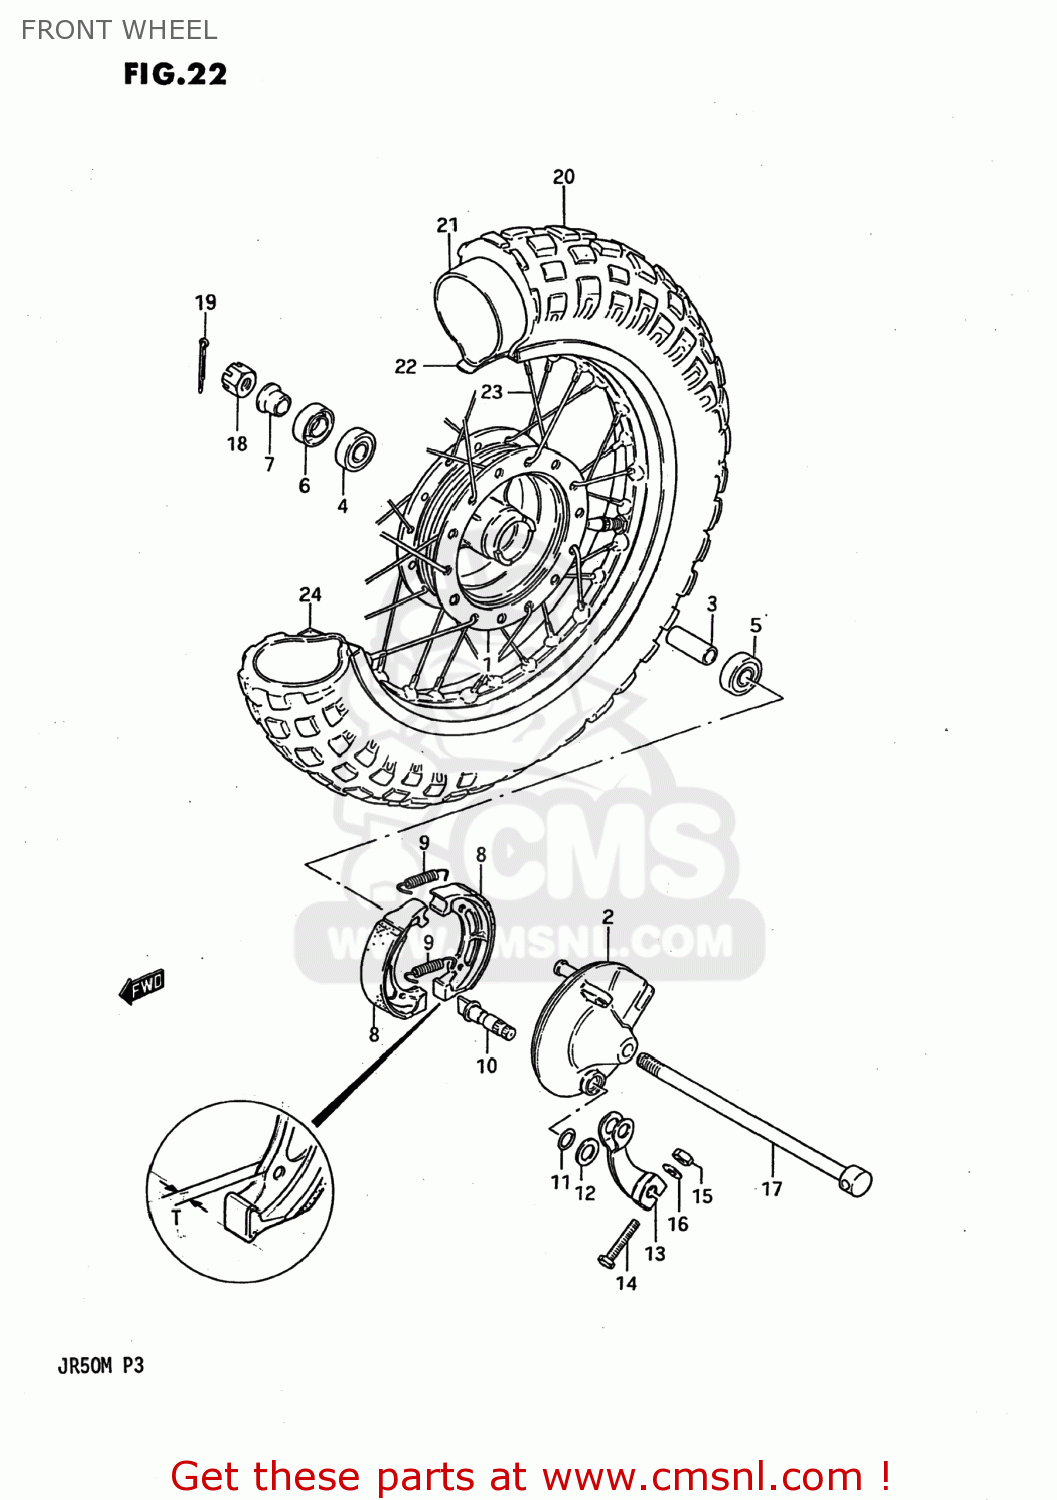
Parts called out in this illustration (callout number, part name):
1	HUB,FR WHEEL
2	PANEL,FR BRAKE ANCHOR
3	SPACER(10.2X16X47)
4	BALL BEARING K
5	BEARING
6	SEAL,OIL(15X27X6)
7	SPACER,AXLE
8	SHOE,BRAKE
9	SPRING(L:34)
10	CAM,FRONT BRAKE
11	O RING(D:2.4,ID:9.8)
12	WASHER (10.5X18X1)
13	LEVER,FR BRAKE CAM
14	BOLT
15	NUT
16	WASHER
17	AXLE,RR
18	NUT
19	PIN 20X20
20	TIRE
21	TUBE,INNER
22	PROTECTOR,INNER TUBE
23	SPOKE SET,RR
24	RIM,WHEEL
